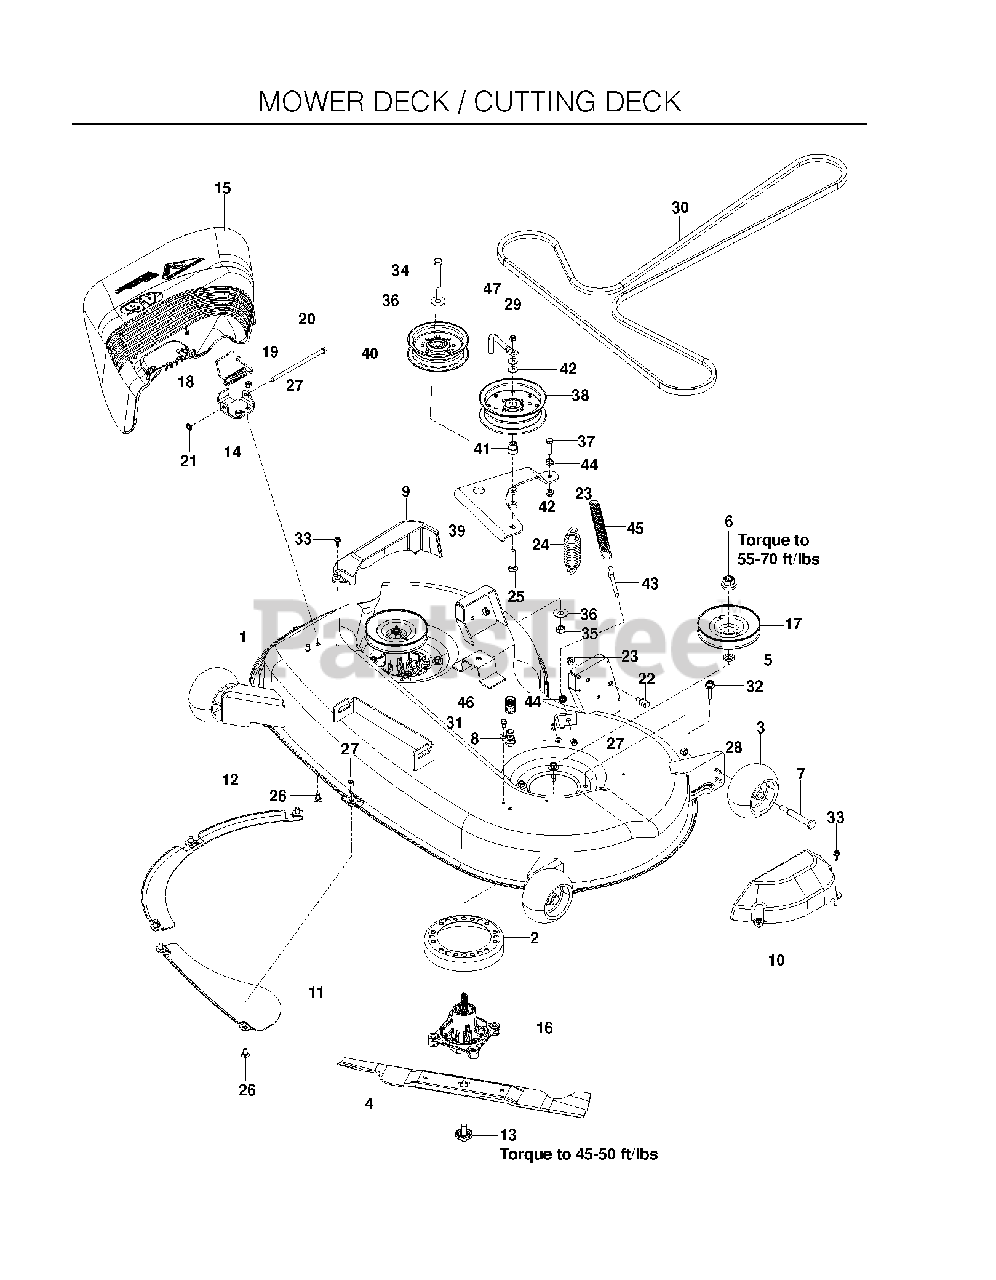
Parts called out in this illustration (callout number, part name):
1	DECK.STAMPED.46".W/DECALS.BLUE
2	STRIPPER-ROUND-UNIVERSAL
3	GAUGE WHEEL
4	BLADE.MOWER.46".HI.LIFT
5	WASHER-SPACER
6	LOCKNUT - 9/16
7	SHOULDER BOLT 1/2X2-5/8 ZD SPE
8	PORT.WASHOUT
9	COVER.MANDREL.RH.46"
10	COVER.MANDREL.LH.46"
11	BAFFLE CENTER FRONT
12	BAFFLE FRONT RH
13	BOLT.WASHER.ASM.7/16-2
14	BRKT.DEFLECTOR.38"2005+
15	SHIELD.DEFLECTOR.MOWER.46"BLAC
16	CUTTER HOUSING
17	PULLEY, DECK
18	TORSION SPRING
19	CAP-SLEEVE
20	ROD, HINGE
21	PUSH NUT
22	STUD.FASTNER.W/ANTI-ROTATE
23	5/16-18 NYLOC FLANGE NUT
25	CARRIAGE BOLT 3/8-16 X
26	BOLT 5/16C X 3/4" CARRIAGE
27	NUT 5/16 NYLOC
28	NUT 3/8-16 NYLOC
29	NUT HEX 3/8-16 NYLON, THIN
31	BOLT 1/4-20 X 1/2 HWST
32	WASHER HEAD SCREW
33	SCREW- 1/4-20 X 5/8
34	BOLT 7/16-14 X 2-1/2 GR 5 ZD
35	7/16-14 HEX NUT W/NYL RING ZD
36	WASHER 7/16 FLAT ZD
37	HCS 5/16C X 1 1/4
38	PULLEY, IDLER
39	ARM, IDLER BLK
40	PULLEY.IDLER.MWR.STATIONARY.LH
41	IDLER BUSHING
42	WASHER 3/8 X 3/4 X .187 TK
43	EYE BOLT 5/16 X 3.50
44	NUT 5/16C WHIZ
45	SPRING, DECK BELT
46	COUPLING.QUICK CONNECT
47	BELT KEEPER 5"
